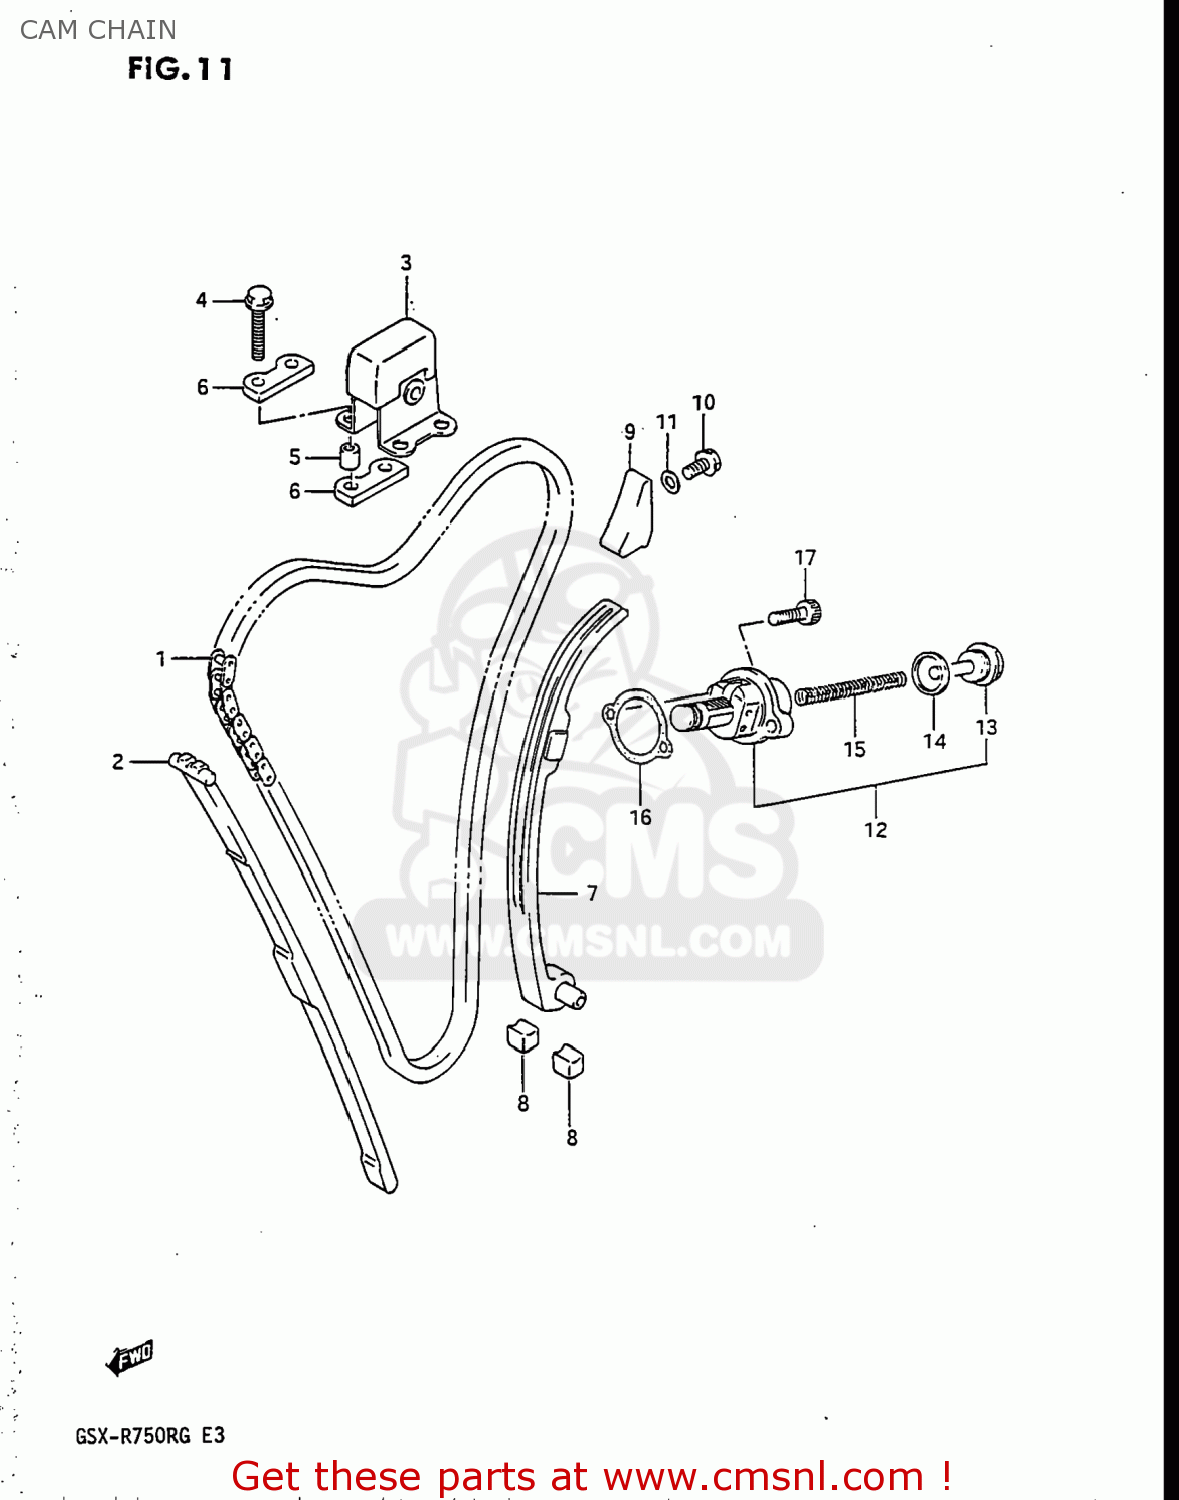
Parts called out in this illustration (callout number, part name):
1	CHAIN,CAMSHAFT DRIVE
2	GUIDE,CAM CHAIN NO.1
3	IDLER,CAM CHAIN
4	BOLT
5	SPACER
6	GUIDE,CAM CHAIN
7	TENSIONER,CAM CHAIN
8	CUSHION,CAM CHAIN TENSIONER
9	GUIDE,CAM CHAIN NO.2
10	BOLT
11	GASKET(5.8X13X1.2) (NAS)
12	ADJUSTER ASSEMBLY,TENSIONER
13	PLUG
14	GASKET (NAS)
15	SPRING
16	GASKET,TENSIONER ADJUSTER (NAS)
17	BOLT
